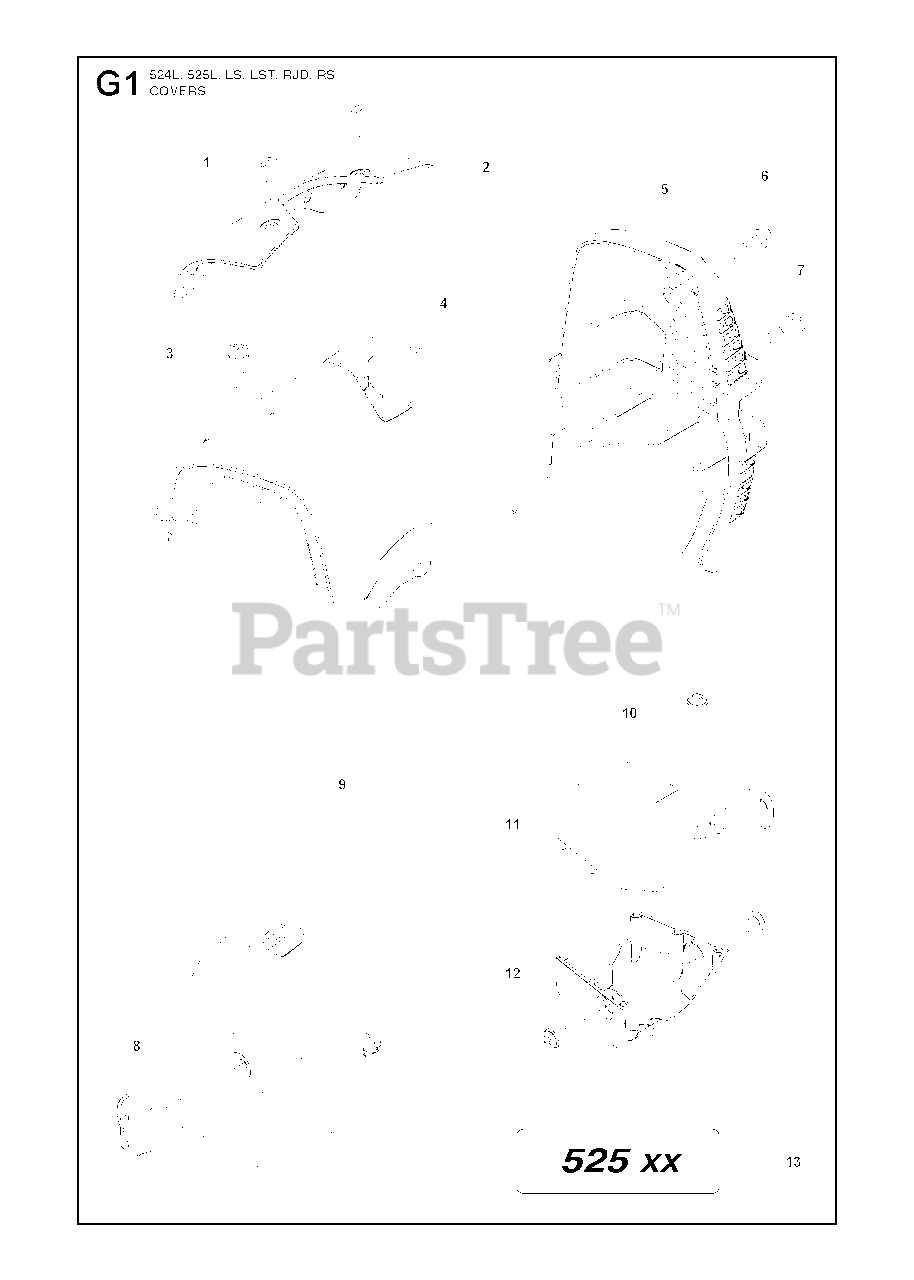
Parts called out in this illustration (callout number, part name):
2	ARM PROTECTION
3	BOLT
4	CYLINDER COVER
5	MUFFLER GUARD
6	BOLT
7	BOLT
8	KNOB CLEANER COLOR:GREY
9	FILTER COVER ASSY
11	COVER CLUTCH HOUSING,UPPER
12	COVER CLUTCH HOUSING,LOWER
